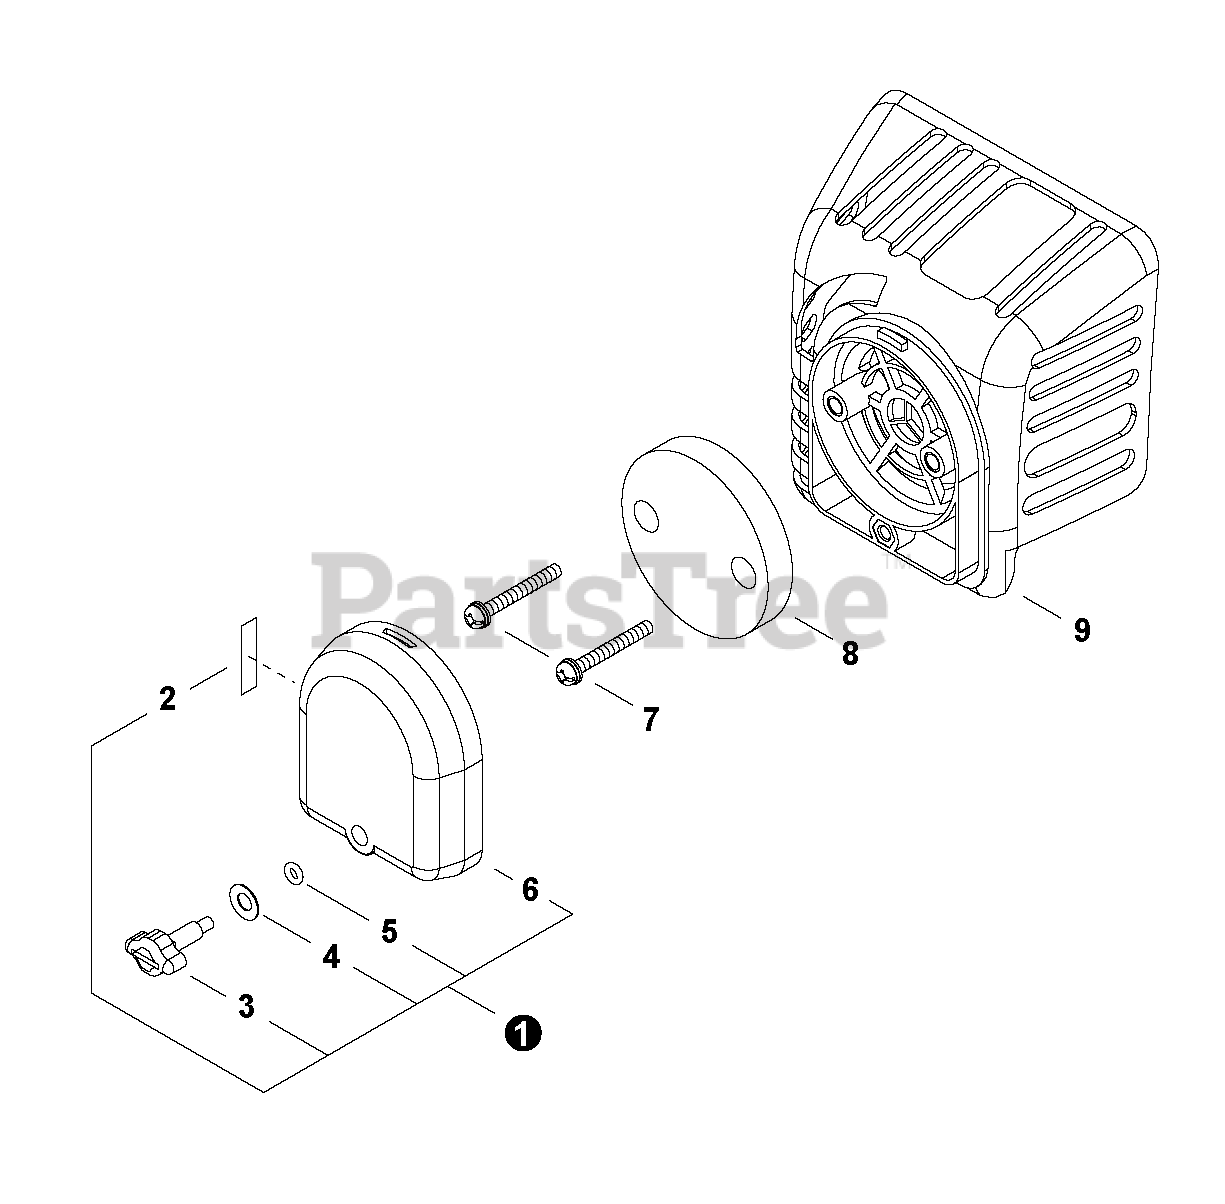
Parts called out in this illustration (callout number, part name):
1	Cover Assy, Air Filter
2	Label, Choke
3	Thumbscrew
4	Washer, Cone M6
6	Cover, Air Filter
8	Filter, Air
9	Case, Air Filter
